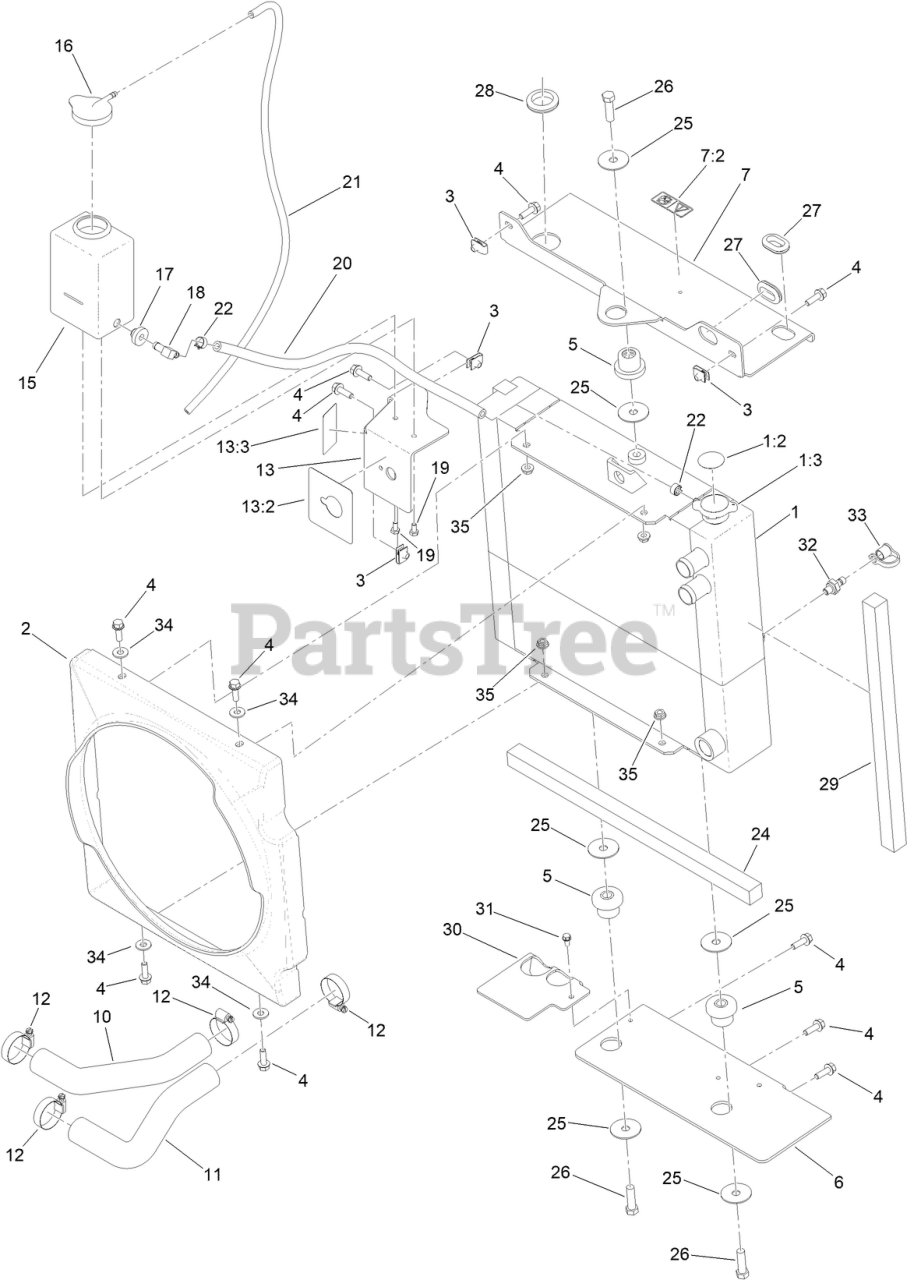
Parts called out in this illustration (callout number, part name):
1	COOLER ASM
1:2	DECAL-CAP, RADIATOR
1:3	CAP - RADIATOR
2	SHROUD-COOLER
3	NUT-CLIP, U
4	SCREW-HHF
5	MOUNT-ISOLATOR
6	PLATE-MOUNT, COOLER
7	BRACKET-COOLER
7:2	DECAL-HOT SURFACE
10	HOSE-RADIATOR, UPPER
11	HOSE-RADIATOR, LOWER
13	BOTTLE BRACKET ASM-RADIATOR
13:2	DECAL-BATTERY DISCONNECT
13:3	DECAL-WARNING, FAN
15	TANK-OVERFLOW
16	CAP-TANK, OVERFLOW
17	BUSHING
18	FITTING-ELBOW, 90 DEG
19	SCREW-HH
20	HOSE-FUEL
21	HOSE-LP
22	CLAMP-HOSE
24	FOAM-RADIATOR
25	WASHER
26	SCREW-HH
27	GROMMET
28	GROMMET-RUBBER
29	FOAM-RADIATOR
30	BAFFLE-AIR
31	SCREW-HWH
32	FITTING
33	CAP-DUST
34	WASHER-FLAT
35	NUT-HF
